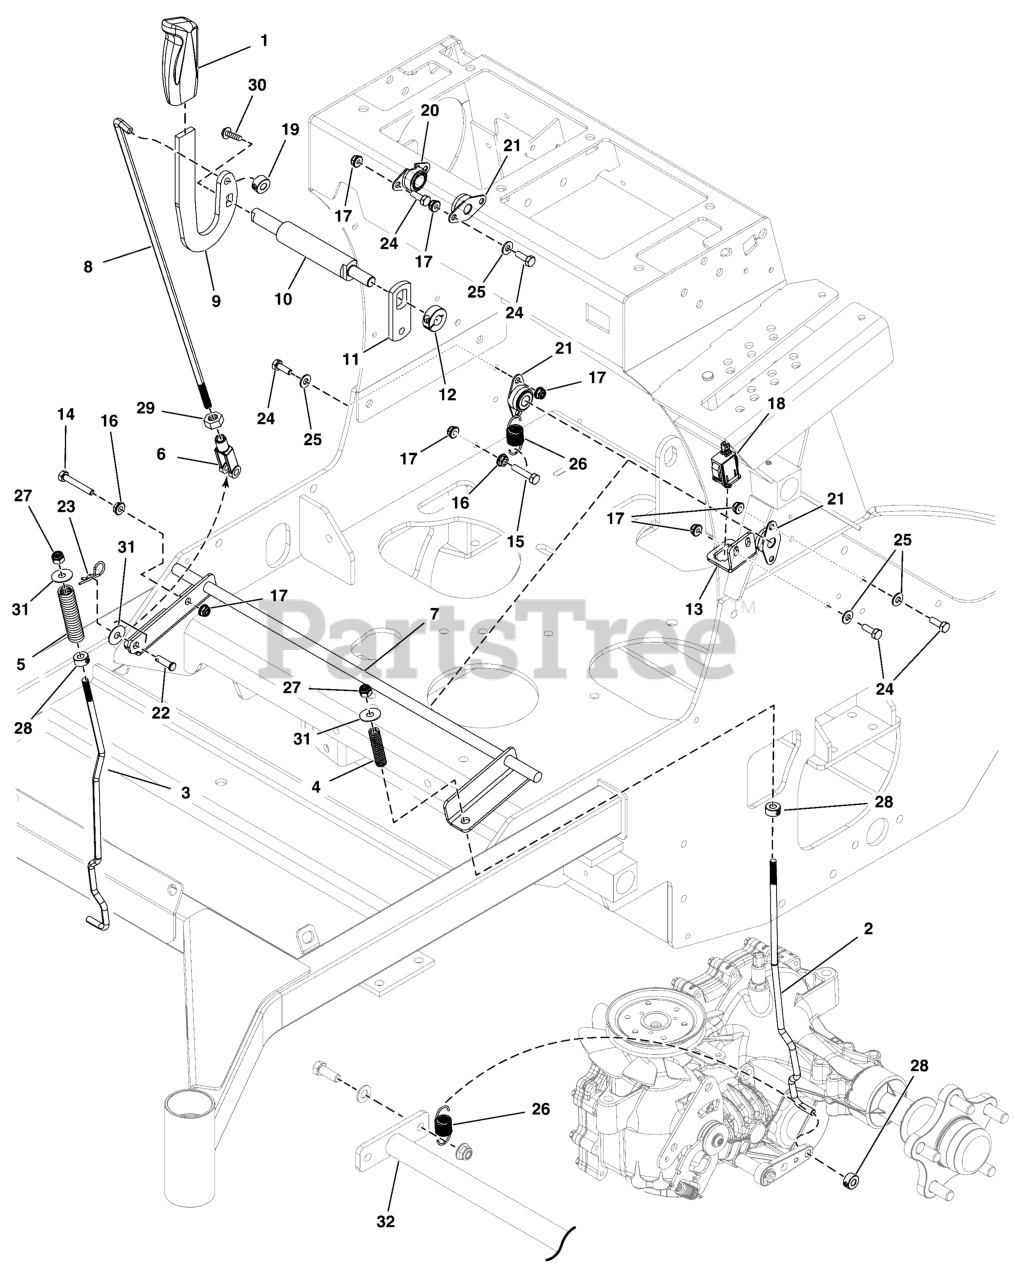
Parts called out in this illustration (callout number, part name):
1	GRIP, BLACK FLEXIBLE
2	ROD, PARKING BRAKE, TRANS-LEFT
3	ROD, PARKING BRAKE, TRANS-RIGHT
4	SPRING-COMP, .375IDX2.75LGX.054WR, SS
5	SPRING-COMP, .496ID X 3.00LG X .112WR
6	CLEVIS, 5/16-24, STEEL, CLEAR ZINC
7	WELD, BRAKE SHAFT, STAND ON - BLK
8	ROD, BRAKE, STAND-ON
9	ARM, Brake
10	SHAFT, UPPER BRAKE ROD, SRSZ
11	PLATE, BRAKE TAB, STAND-ON
12	COLLAR, 1/2 SET (1/2 SPLIT COLLAR IN MODEL)
13	PLATE, BRAKE SWITCH, STAND ON
14	BOLT, 1/4 X 20 X 1-3/4 GD5 YZ
15	BOLT, 1/4-20 X 1-1/4 GD5 CZ
16	NUT, 1/4-20 HEX SERR. FLANGE
17	NUT, 1/4-20 Hex Nylock Flange
18	SEE ELECTRICAL GROUP
19	COLLAR, 5/16" Set
20	BEARING, 5/8" FLANGED, PLASTIC BALL
21	BEARING, 1/2 FLANGED, PLASTIC BALL
22	PIN, CLEVIS, 5/16 X 1, PLATED
23	PIN, HAIR, .0585 X 1-1/8, 1/4 EYE, YZ
24	BOLT, 1/4"-20 X 3/4" GD5 YZ
25	WASHER, 1/4 SAE
26	SPRING-EXT, .740 ODX2.025LGX.072WR, BLK
27	NUT, 5/16-24 HEX NYLON LOCK
28	COLLAR, DOUBLE SPLIT, 7MM
29	NUT, Hex, 5/16-24
30	SCREW-HEX SEMS WSHR 1/4-20 X.88 DOG PT
31	WASHER, 5/16" USS
32	SEE MAIN FRAME GROUP
